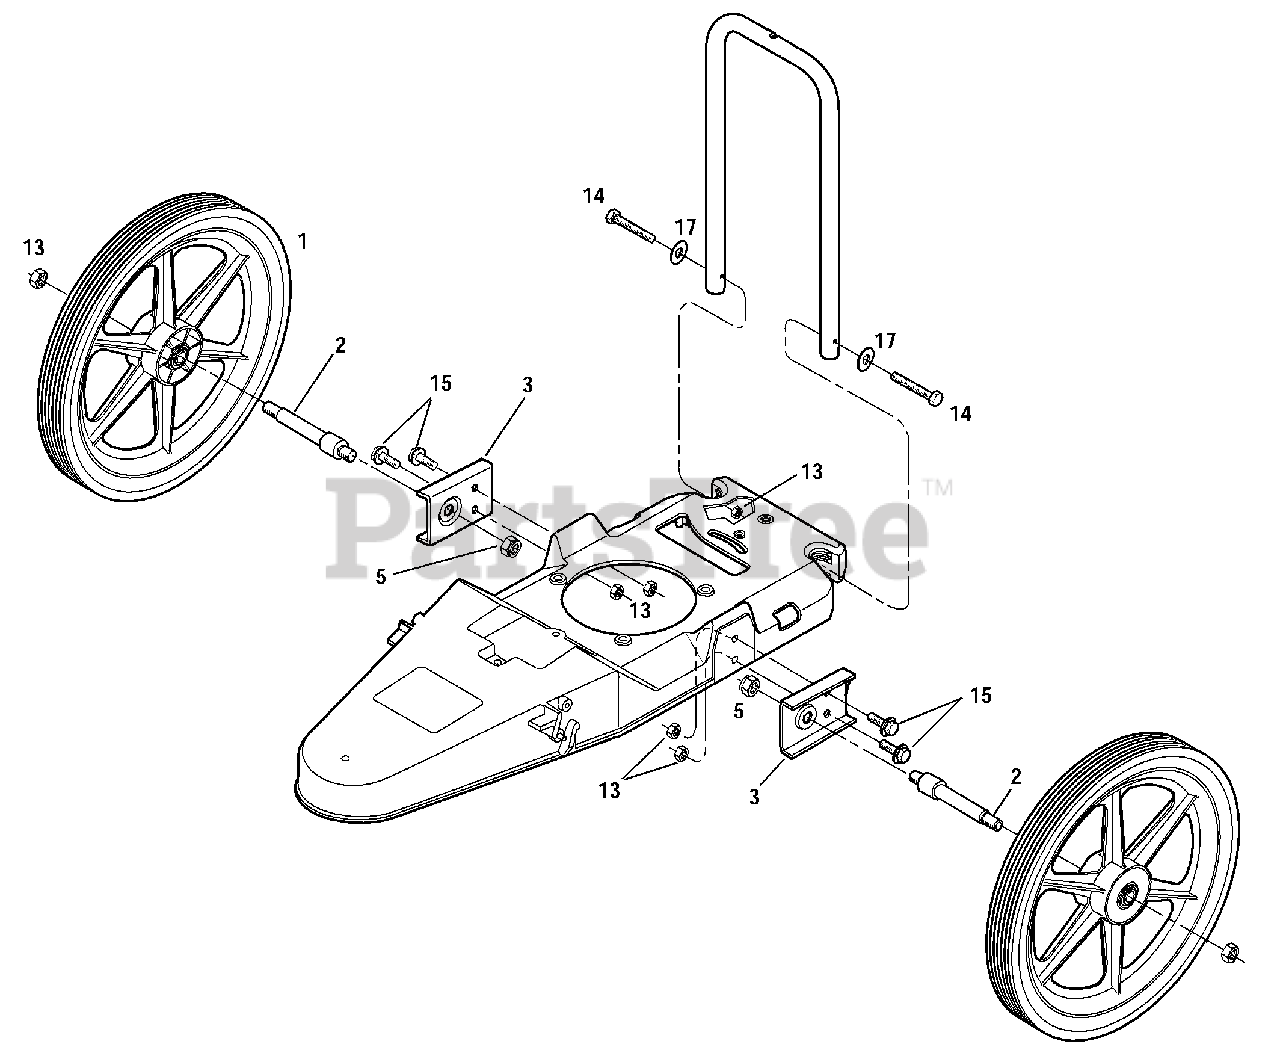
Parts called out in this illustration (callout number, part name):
1	Wheel - 6 spoke
2	Wheel Stud
3	Wheel Mounting Bracket
5	Top Lock Nut, 3/8-16
13	Hex Lock Nut, 5/16-18
14	Hex Head Bolt, 5/16-18 x 2
15	Hex Flange Screw, 5/16-18 x 1
17	Washer, 5/16 ID
